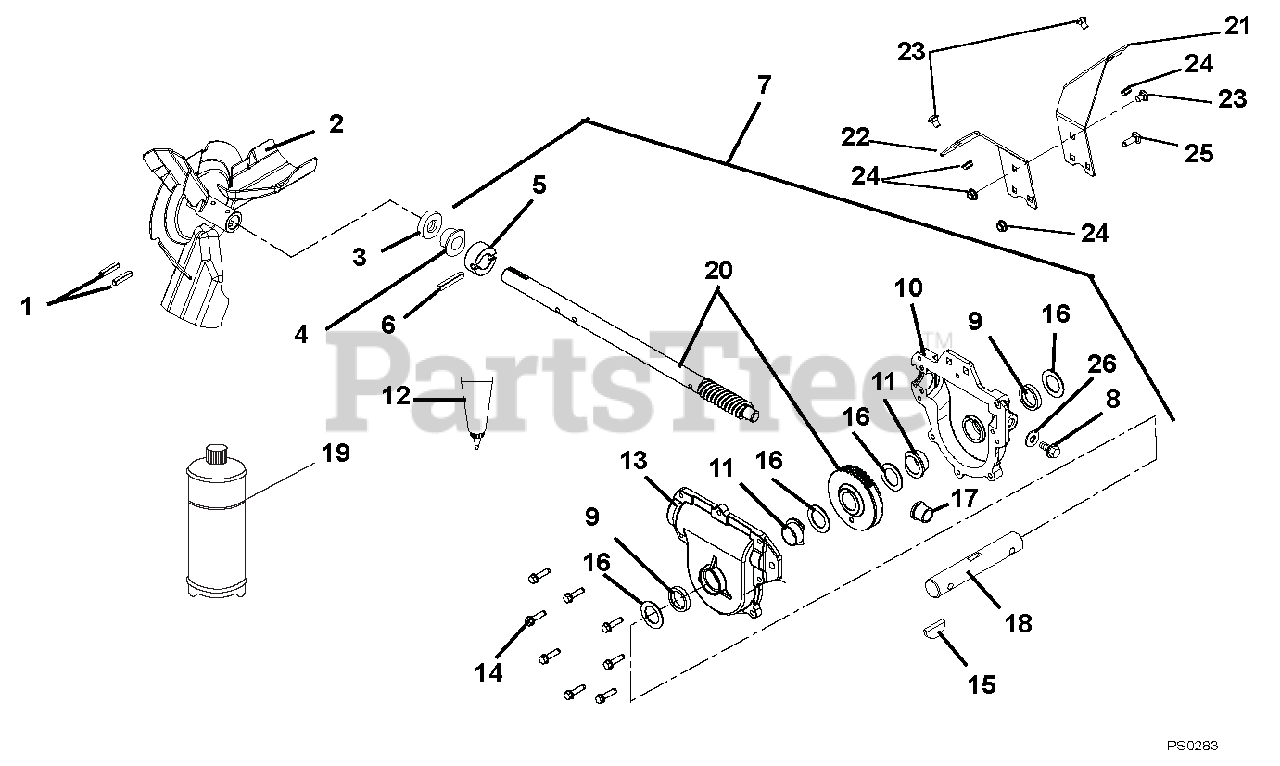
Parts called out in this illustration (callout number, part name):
1	PIN-ROLL .250X1.75
2	IMPELLER, 3 BLADE-14"
3	SEAL-OIL .875X1.375X.25 RBR OD
4	BSHG-FLG .876 X 1.500 X .750
5	THRUST COLLAR, .875" ID
6	PIN-GRV .250X1.50 TP E
7	GEAR CASE ASSEMBLY - COMMON
8	SCR-TAP .38-16X.75 ROLOK YZ WX
9	SEAL-OIL 1.000X1.375X.250
10	GEARCASE, ALUMINUM, LH
11	BSHG-FLG 1.003X1.5X.625
12	LOCTITE 518 GASKET--6ML TUBE
13	GEARCASE, ALUMINUM, RH
14	@SCR-TAP .25-20X1.00 HWH TR YZ
15	KEY-WDRF .25X.875 HRD #A
16	WSHR-FL-STL 1.010X1.505X.062YZ
17	BSHG-FLG .629 X 1.000 X .750
18	RAKE SHAFT, SHORT-COMMON
19	ARIENS 16 OZ.BOTTLE OF L2 LUBE
20	WORM SHAFT & GEAR
21	BRACKET, GEAR CASE SUPPORT-LH
22	BRACKET, GEAR CASE SUPPORT-RH
23	@BLT-RHDSSQNK .31-18X.62 G5YZ
24	@NUT-LK-TOP-FLG .31-18 YWZC
25	@BLT-RDHDSQNK .31-18X1.00 G5YZ
26	WSHR-FIBER .437X.656X.032
